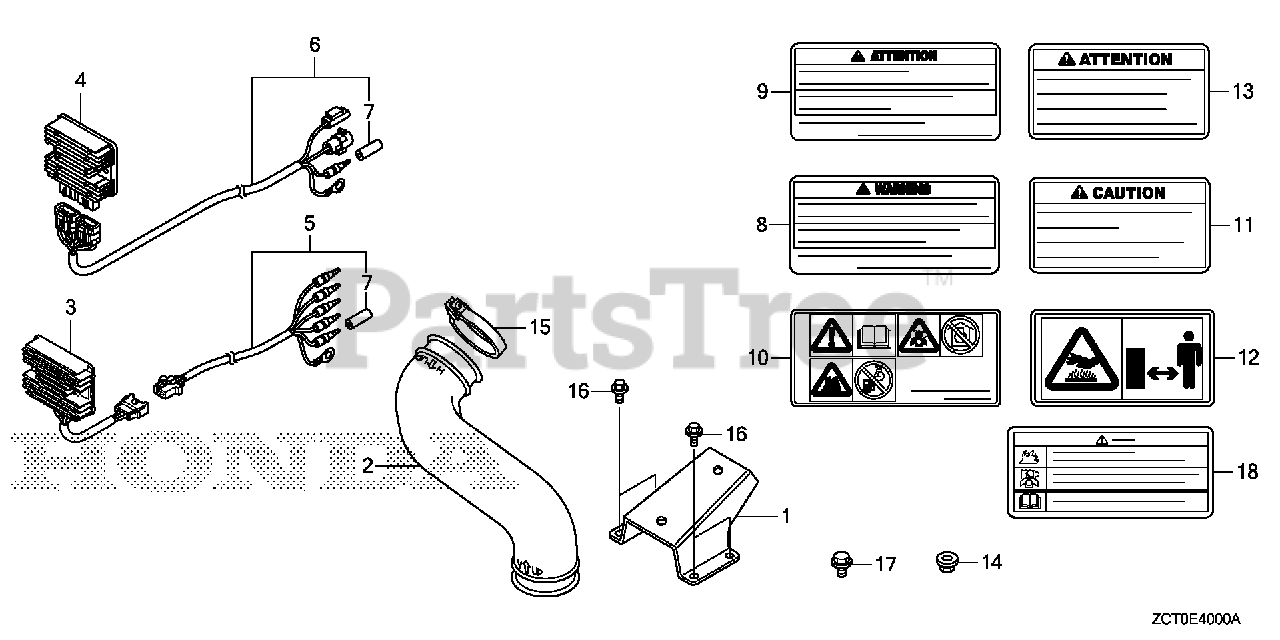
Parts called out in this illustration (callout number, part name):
4	RECTIFIER ASSY., REGULATOR (30A)
6	SUB-WIRE HARNESS ASSY.
7	PLUG, CONNECTOR (OUTER)
9	MARK, OPERATOR CAUTION (FRENCH)
10	MARK, OPERATOR CAUTION (PICTOGRAPH)
11	MARK, EX. CAUTION (ENGLISH)
12	MARK, EX. CAUTION (PICTOGRAPH)
13	MARK, EX. CAUTION (FRENCH)
14	NUT, FLANGE (8MM)
